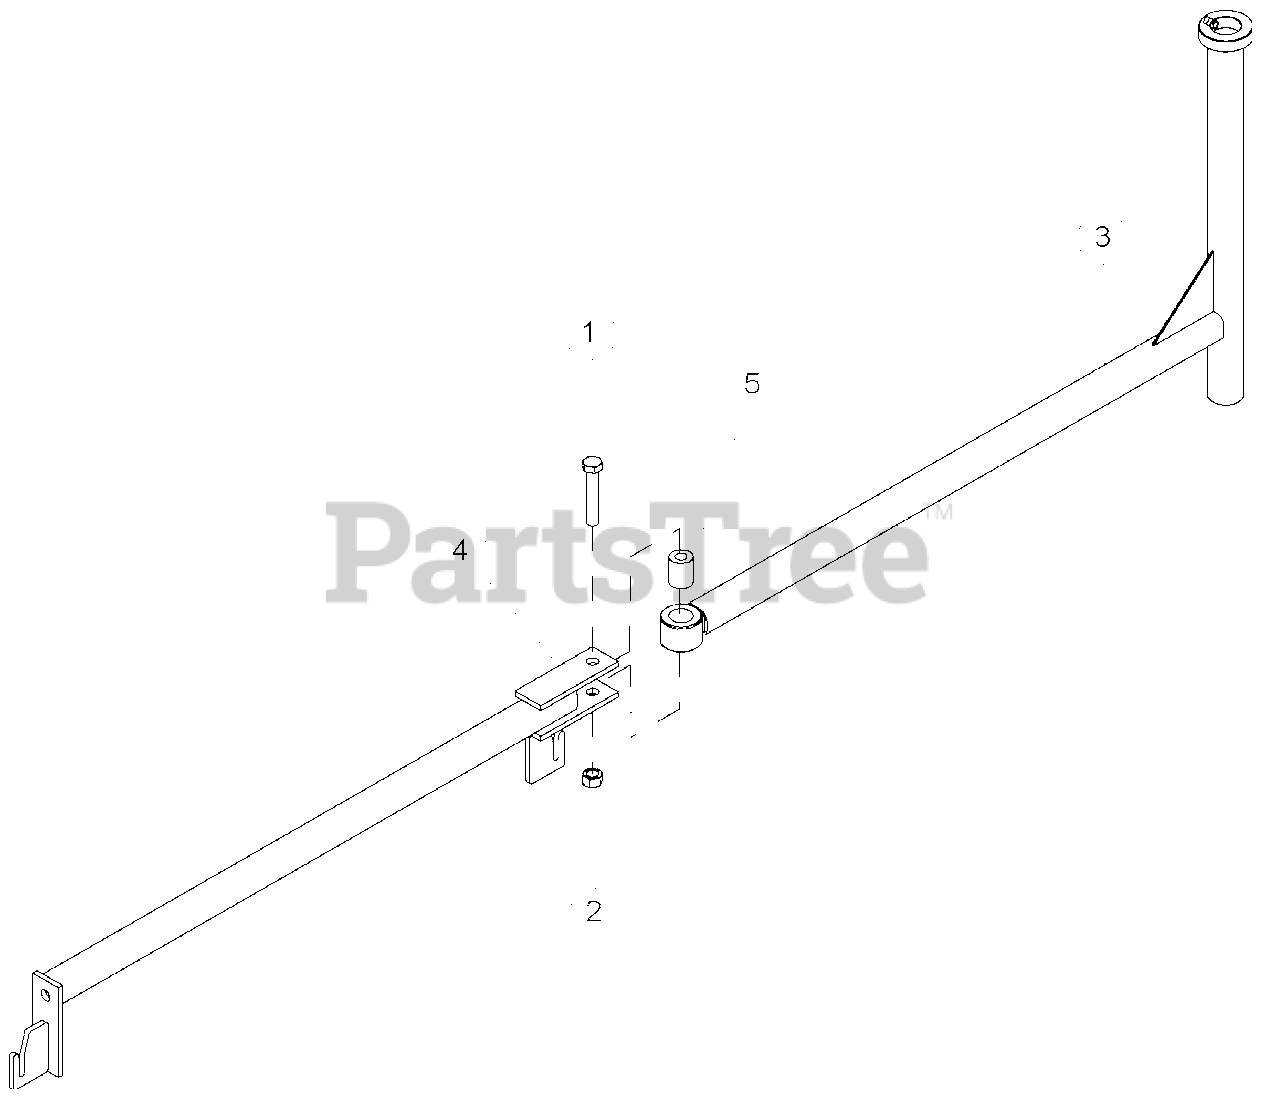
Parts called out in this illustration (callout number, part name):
1	BOLT, 1/2" X 2-3/4" HEX HD
2	NUT, 1/2" CENTERLOCK GRB ZP
3	WELDMENT, HOSE SUPPORT
4	WELDMENT, HOSE SUPPORT
5	SPACER, 1.00 OD X 0.25 X 1.26
